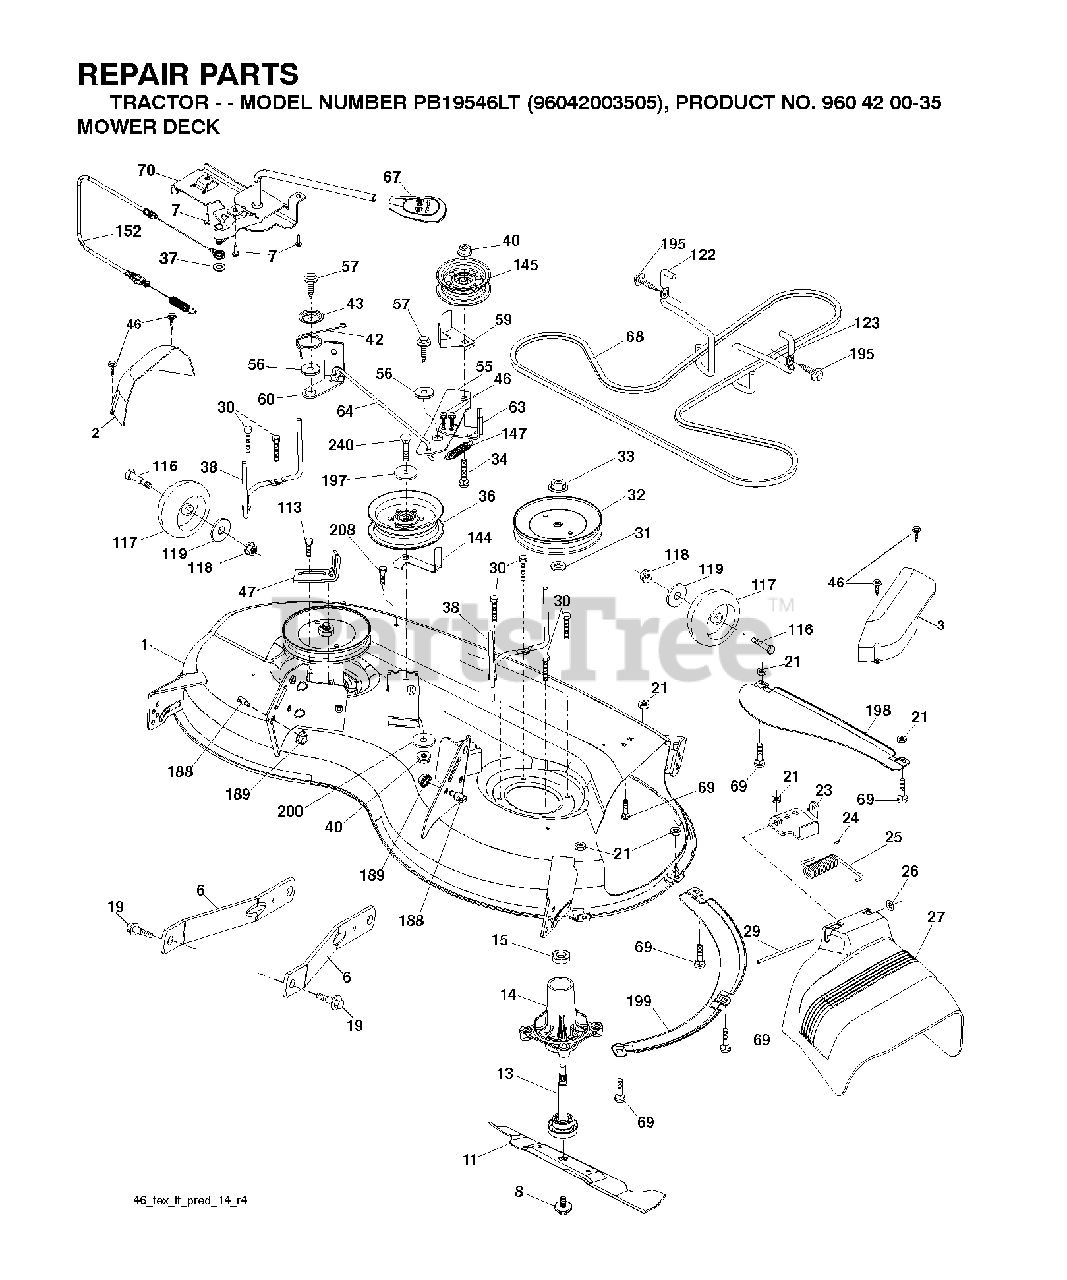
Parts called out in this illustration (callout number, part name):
1	DECK.WELDMENT.46"
2	COVER.MANDREL.LH.46"
3	COVER.MANDREL.RH.46"
6	ARM.SUSPENSION.MOWER.R
7	SCREW.#10 X 0.750.BOS (2 2)
8	BOLT.WASHER.ASM.7/16-2
11	BLADE.MOWER.46".HI.LIFT
11	BLADE, 46" MULCH
13	SHAFT.ASM.MDRL.N/GREASE.38
14	HOUSING.MANDREL.4PT.
19	BOLT.SHOULDER
21	LOCKNUT
23	BRKT.DEFLECTOR.38"2005+
24	CAP-SLEEVE LT
25	SPRING.TORSION.DEFLECT
26	NUT PUSH M
27	SHIELD.DEFLECTOR.MOWER.46"BLK
29	ROD.HINGE
30	SCREW, WASHER HEAD
31	WASHER.SPACER.MANDREL
32	PULLEY.MANDREL.5.438.PD
33	NUT.FLANGE.LOCK.TOP
34	BOLT.3/8-16X1.50
36	PULLEY.IDLER.2006
38	KEEPER.BELT.MANDREL.PULLEY
40	NUT LOCK FLG 3/8-16 UNC
42	SPRING.TORSION.BRAKE
43	SRPING.TORSION.RETAINE
46	SCREW.1/4-20X5/8
47	BRKT.CLUTCH.CABLE
55	IDLER.ARM
56	SPACER.RETAINER
57	SCREW 3/8-16X1
59	GUARD, BELT
60	ARM BRAKE MOWER RH 38"
64	LINKAGE BRAKE
67	HANDLE.CLUTCH.CABLE.LT
68	V-BELT
69	BOLT
70	CLUTCH.ASM.MANUAL.LT.TEX
113	BOLT.5/16HEX.WHS.HD
116	BOLT M
117	WHEEL.GAGE.HALF.SPOKED
118	LOCKNUT
119	WASHER
122	KEEPER BELT ENGINE LH
123	KEEPER BELT RH
144	KEEPER.BELT.MOWER
145	PULLEY.IDLER.48"PRIMARY
147	SPRING RETURN
152	CABLE.CLUTCH.MANUAL.
188	STUD.FASTNER.W/ANTI-ROTATE
189	NUT LOCK HEX FLANGE 5/16-18
195	SCREW, 3/8-16X3/4
197	WASHER
198	BAFFLE CENTER FRONT
199	BAFFLE FRONT RH
200	WASHER.13/32 X 1 X 1/2.11GUARD
208	SCREW 3/8-16X1/2
240	BOLT-HEX EAK
